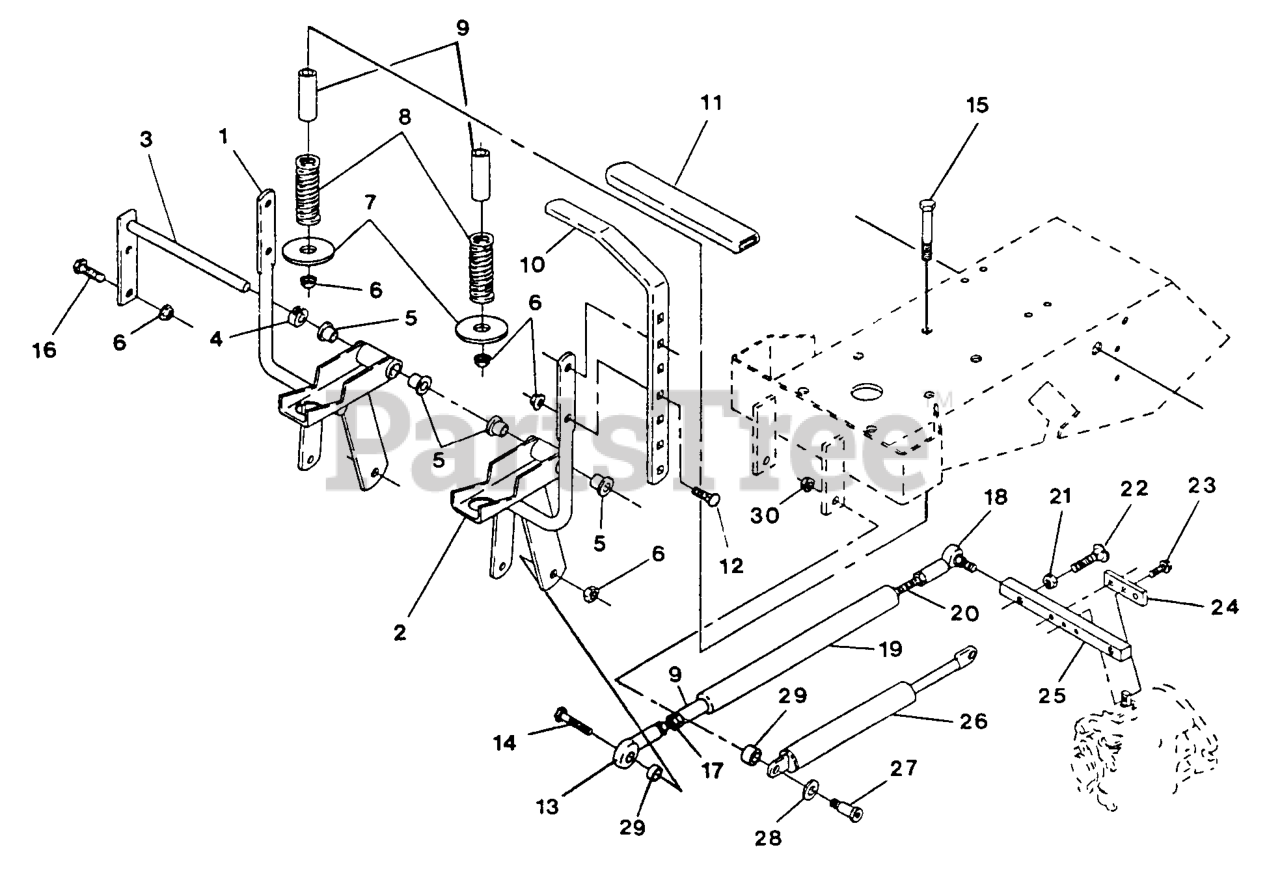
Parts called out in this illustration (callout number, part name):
5	BEARING-CONTROL
7	WSHR,REVERSE INDICATOR
8	SPRING-INDICATOR, REVERSE
9	BUSHING,SPRING GUIDE
11	GRIP,MOTION CONTRL
13	BALLJOINT-RH
18	BALLJOINT
20	ROD,STEERING
24	PLATE,CLAMP
25	ARM,PUMP CONTROL
29	SPACER-PLATED
